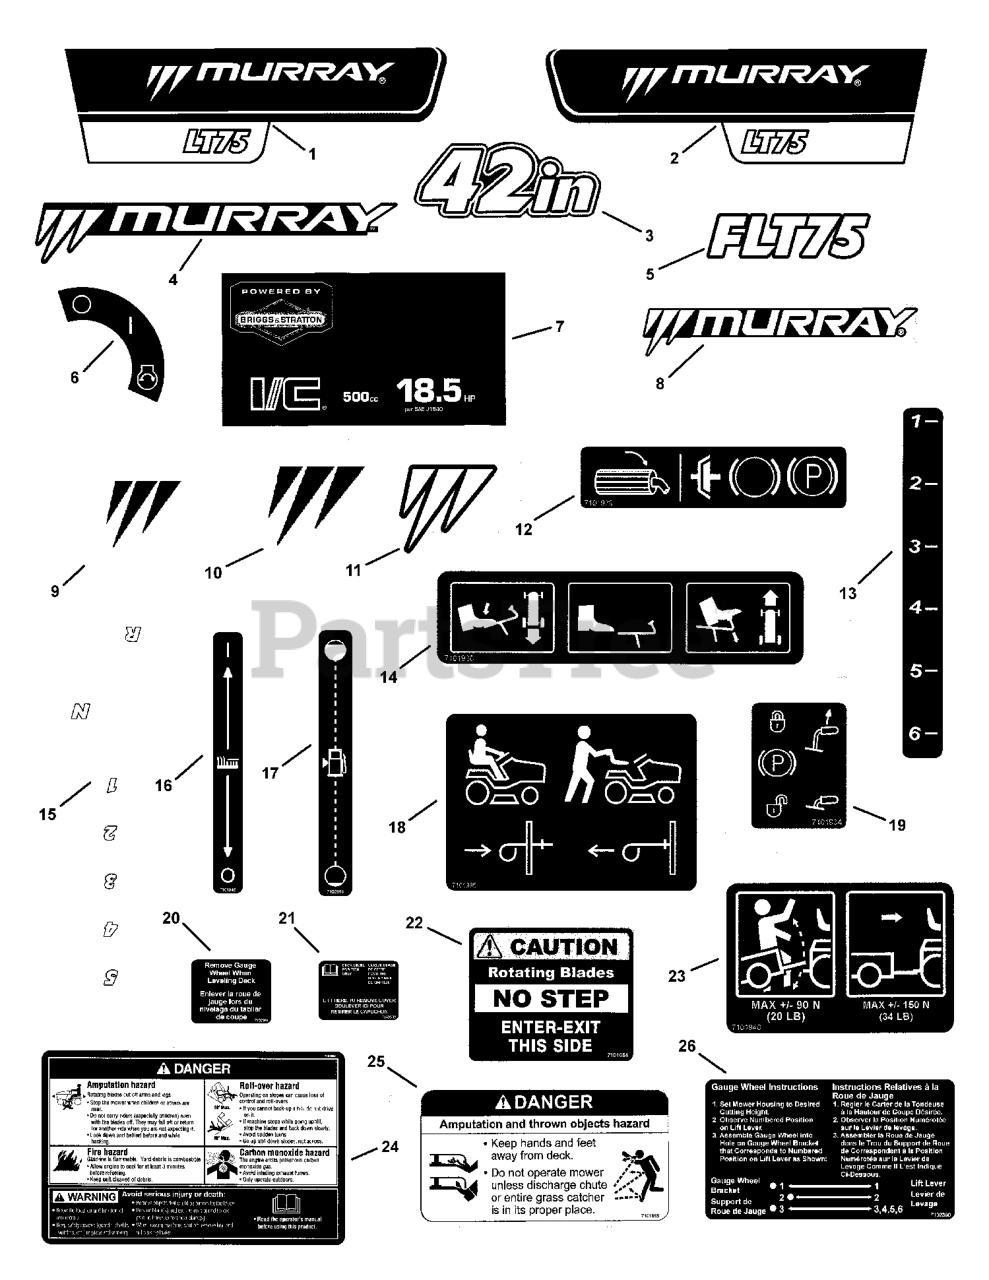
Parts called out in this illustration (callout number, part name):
1	MURRAY NAME PLATE, RH
2	MURRAY NAME PLATE, LH
3	42" DECK DECAL, MURRAY
4	MURRAY NAME PLATE, REAR
5	DECAL, FLT75,
6	DECAL, IGNITION, RZT
7	DECAL, BRIGGS HP 15.5
7	DECAL, BRIGGS HP 18.5
7	DECAL, BRIGGS HP 13.5
8	DECAL, MURRAY LOGO, VENT
9	DECAL, STEERING WHEEL HUB
10	DECAL, FRONT HOOD
11	DECAL, MURRAY ICON, BLACK/GRAY
12	DECAL, BELT / CLUTCH
13	CUTTING HEIGHT DECAL, MURRAY
14	DECAL, DRIVE PEDAL
15	MANUAL DRIVE DECAL
16	DECAL, MANUAL PTO
17	DECAL, FUEL GAUGE LONG
18	DECAL, ROLL RELEASE
19	DECAL, PARK BRAKE
20	DECAL, DECK LEVEL ENG/FC
21	DECAL, DECK LEVEL POSITION ENG/FC
22	DECAL, NO STEP FC
22	DECAL-NO STEP
23	DECAL, WEIGHT LIMITATION
24	DECAL, DANGER FC
24	DECAL-UMBER
25	DECAL, CUT HAND/FOOT FC
25	DECAL-DANGER DO NOT OPERATE W/O DEFLECTOR
26	DECAL, GAUGE WHL INST ENG/FC
